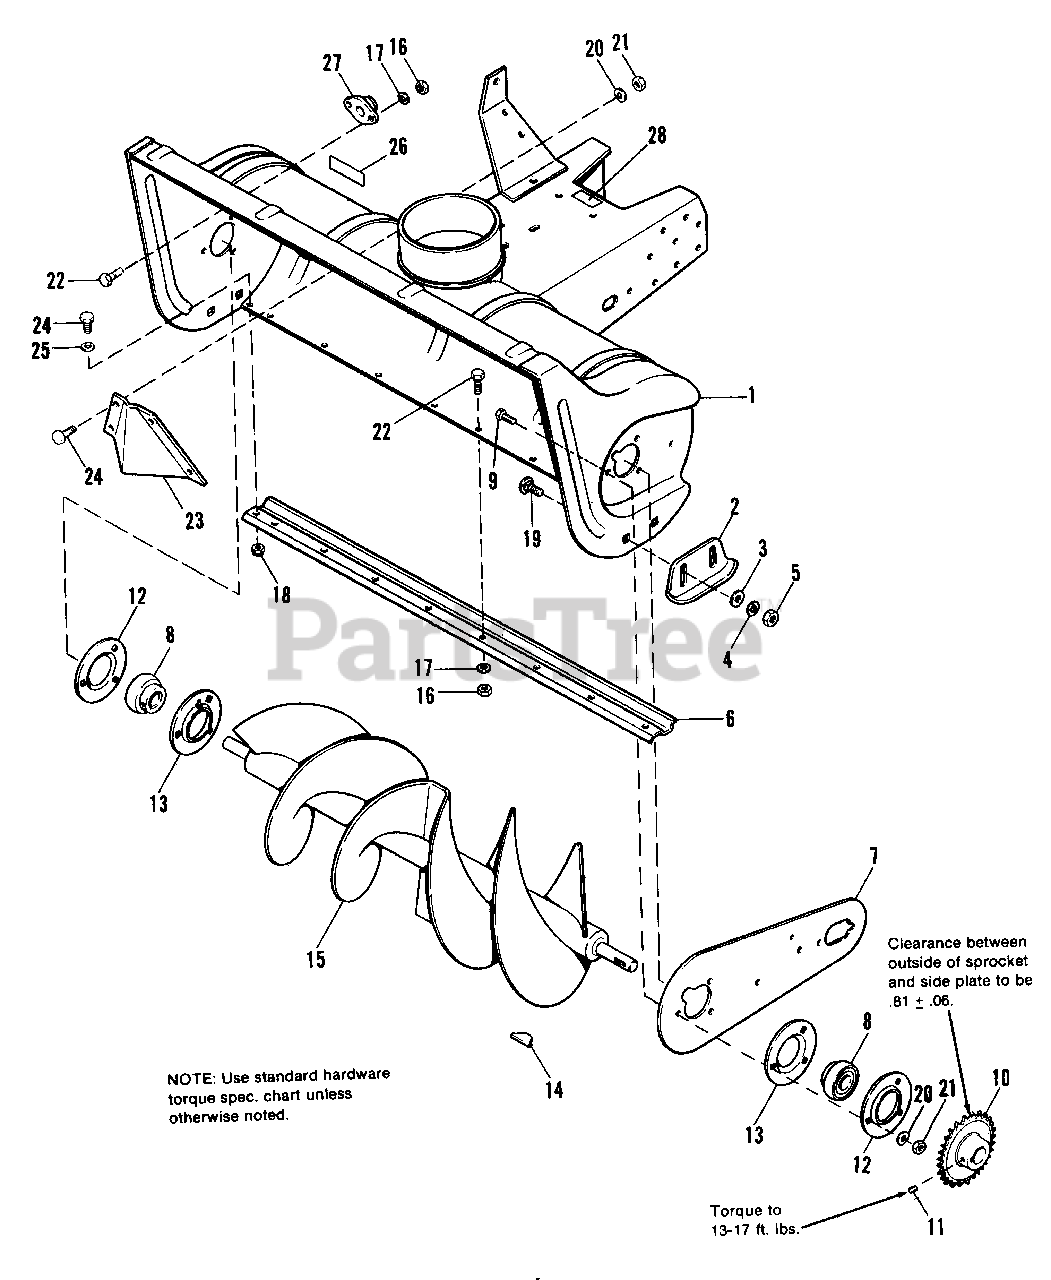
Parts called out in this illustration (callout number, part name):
1	BODY & FRAME ASSY. (1690547 Only)
1	BODY & FRAME ASSY. (1690548 only)
3	WASHER, Plain, 3/8
4	LOCKWASHER, 3/8
5	NUT, Hex, Full, 3/8-16
6	SCRAPER, Body (1690547 Only)
6	SCRAPER, Body (1690548 only)
7	PLATE, Side
8	BEARING, Cartridge
9	CAPSCREW, Hex, 5/16-18 x 3/4
10	SPROCKET, Rotor
11	SETSCREW, 5/16-18 x 5/16
12	FLANGE, Bearing
13	FLANGE, Bearing
15	ROTOR ASSY. (1690547 Only)
15	ROTOR ASSY. (1690548 only)
16	NUT, Hex, Full, 1/4-20 (Qty. 10 on 1690548)
17	LOCKWASHER, 1/4 (Qty. 10 on 1690548)
18	LOCKNUT, Hex, 5/16-18
19	BOLT, Carriage, 3/8-16 x 3/4
20	LOCKWASHER, 5/16
21	NUT, Hex, Full, 5/16-18
22	CAPSCREW, Hex, 1/4-20 x 5/8 (Qty. 10 on 1690548)
24	CAPSCREW, Hex, 5/16-18 x 5/8
25	WASHER, Plain, 1/4
26	DECAL, Safety
28	PLATE, I.D.
